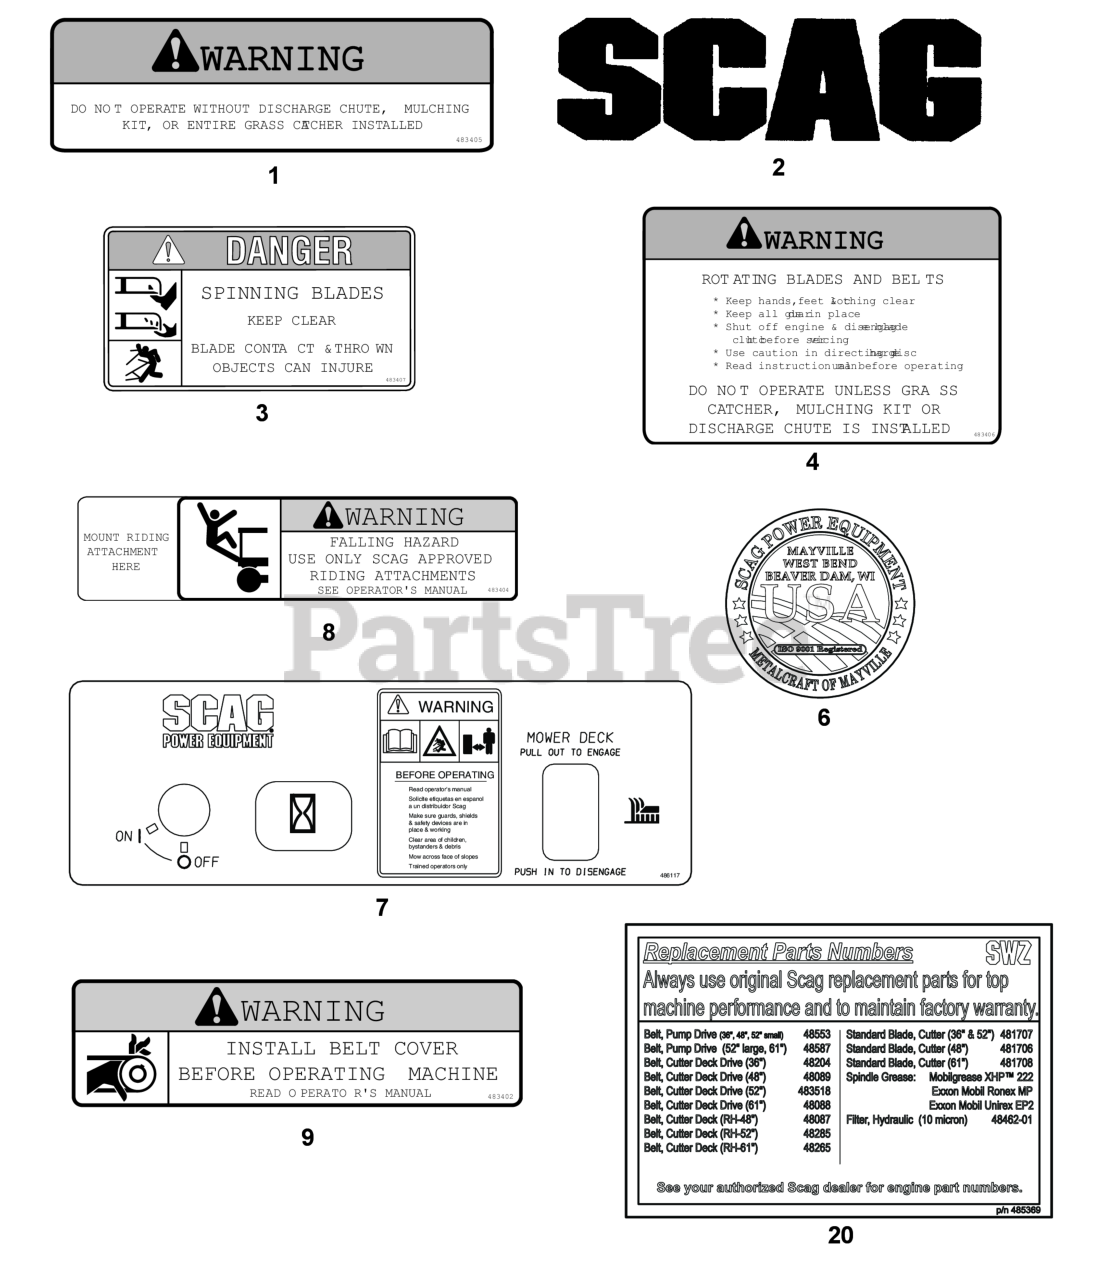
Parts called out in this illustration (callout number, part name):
1	Decal, Warning-Discharge
2	Decal, Scag Logo ( Cutter Deck)
3	Decal, Danger-Spinning Blades
4	Decal, Warning - Rotating Blades
6	Decal, Metalcraft - USA
7	Decal, Instrument Panel - Rear
8	Decal, Sulky Attachment
9	Decal, Warning - Belt Cover
20	Decal, SWZ Replacement Parts
